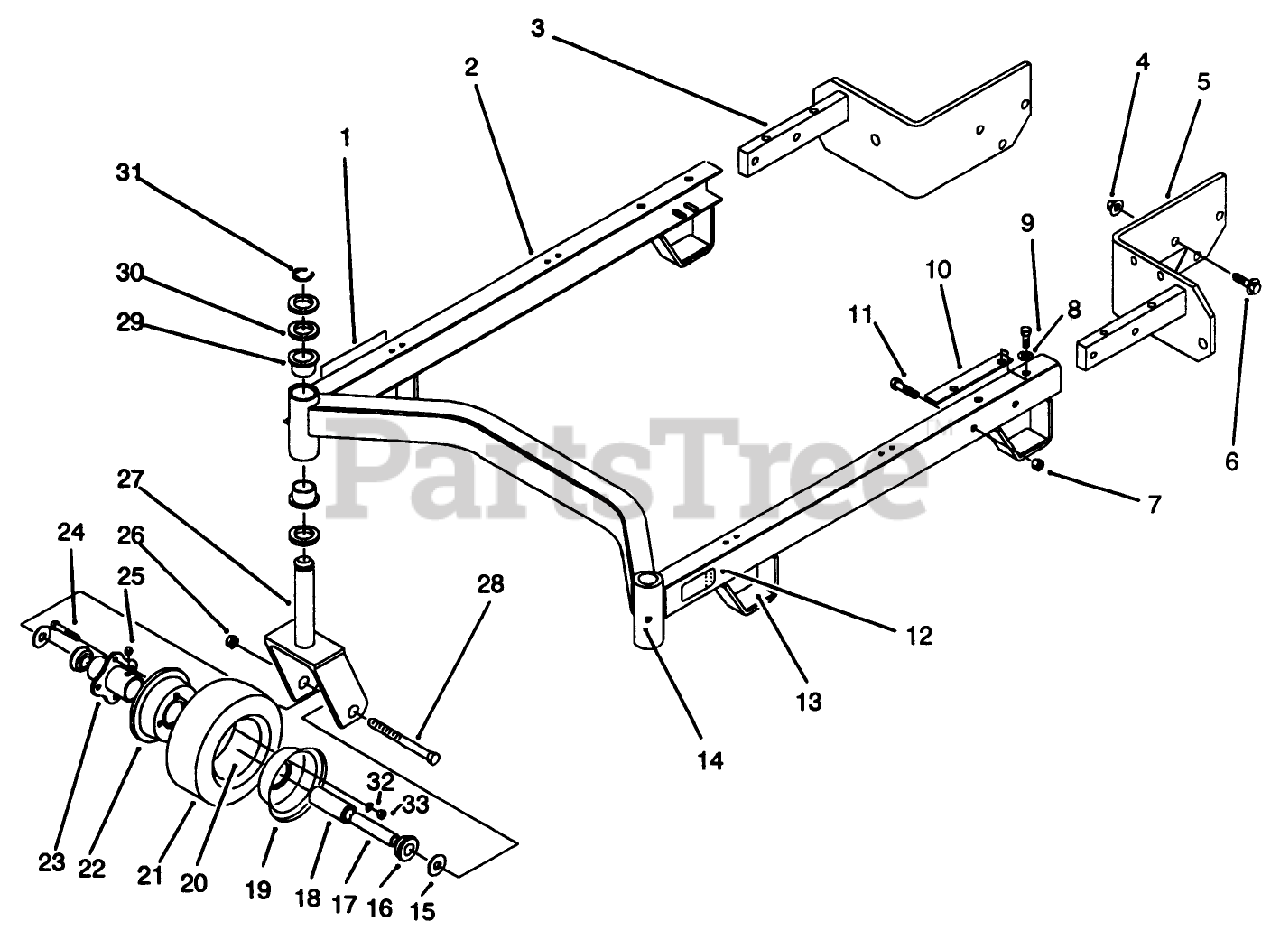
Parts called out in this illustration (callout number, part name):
1	DECAL-HOC, RH
2	Suspension Frame W.A.
3	Bracket RH
4	NUT-HF
5	Bracket-LH
6	SCREW-HHF
7	NUT-LOCK, CONE
8	WASHER-FLAT
9	SCREW W/PATCH
10	SHIM-CARRIER
11	SCREW-HH
12	DECAL-HOC, LH
13	CUSHION-RUBBER
14	FITTING-GREASE
15	WASHER-FLAT
16	BEARING-OUTSIDE
17	SPANNER-TIRE
18	BEARING-ROLLER
19	MALE WHEEL HALF
20	TUBE-INNER (W/VALVE)
22	FEMALE WHEEL HALF
23	HUB-CENTER
24	WHEEL BOLT
25	FITTING-GREASE
26	NUT-HEX
27	Castor Fork
28	SCREW-HH
29	Bushing
30	WASHER-THRUST
31	RING-RETAINING
32	WASHER-LOCK
33	NUT-HEX
